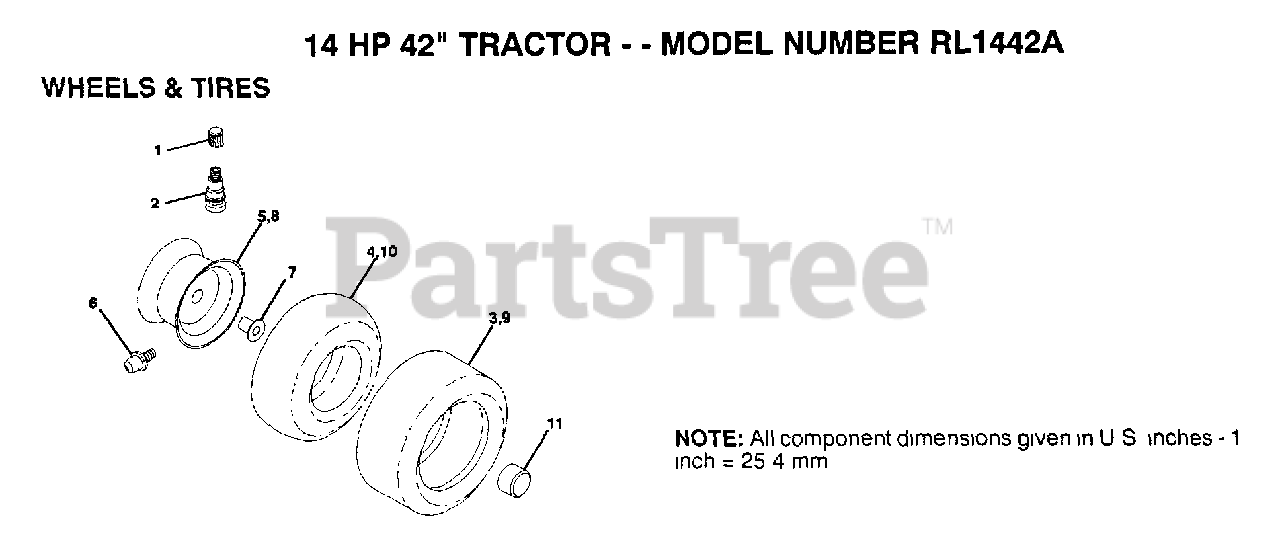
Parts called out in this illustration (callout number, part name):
1	VALVE CAP
2	VALVE STEM LT
4	TUBE.5.3/4.5/6
6	FITTING LT
7	"FLANGE, BEARING"
10	TUBE.18X9.5-8
11	HUB CAP
